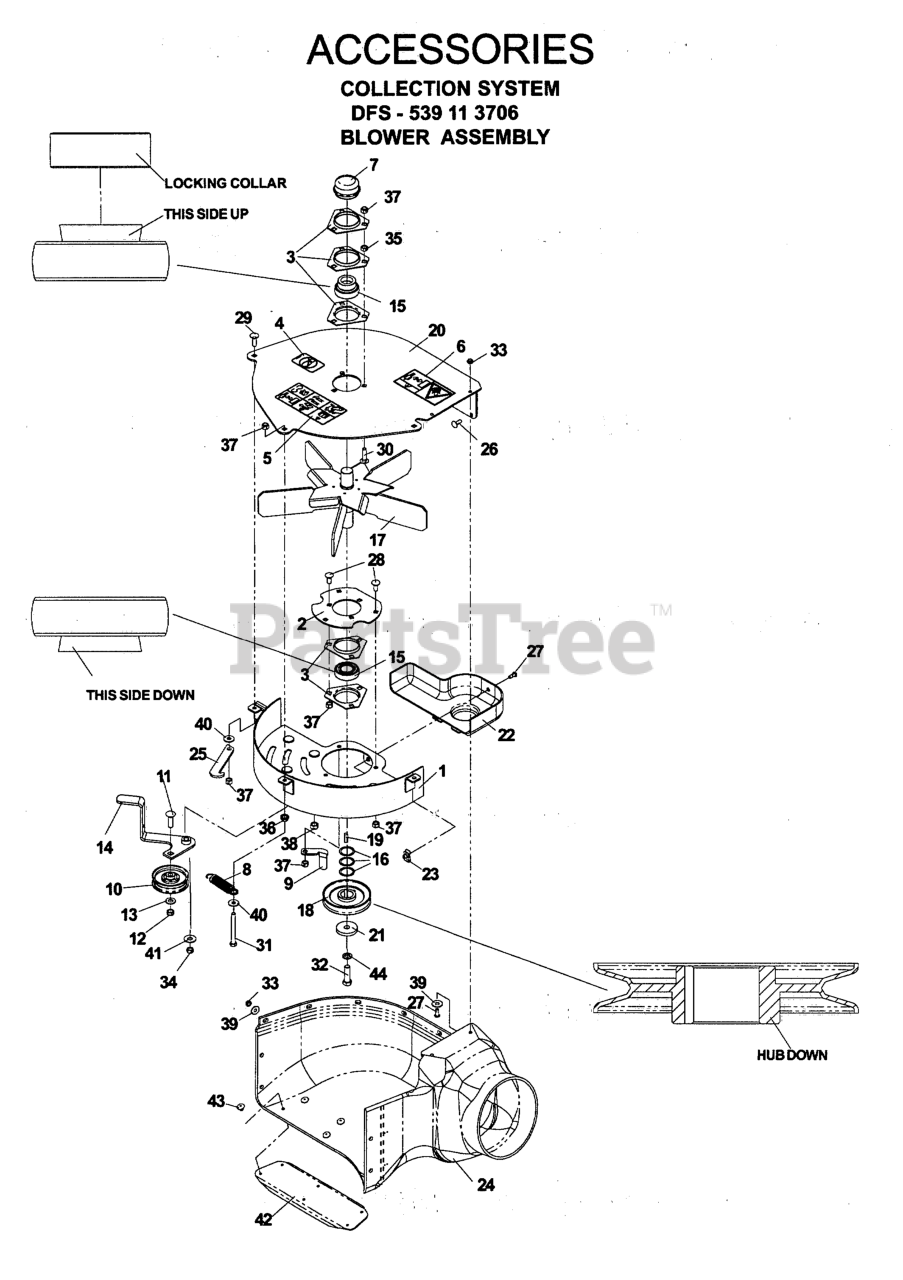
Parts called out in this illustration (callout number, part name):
1	FLOOR WELDMENT
2	BEARING PLATE
3	BRG FLANGE
4	DECAL, NO STEP
5	DECAL, EURO WARNING
6	EURO DECAL, IMPELLER
7	GREASE CAP
8	SPRING-TRANS
9	BELT GUIDE
11	RHSNB 3/8-16 X 1-1/4
12	NUT HEX 3/8-16 NYLON, THIN
13	WASHER 3/8 SAE FLAT
15	BEARING KIT-2 PCS
16	BUSHING.MACHINE.18.GAUGE
17	SPINDLE BLOWER FAN
19	KEY 1/4 SQ X 3/4
20	FAN COVER W/DECALS
21	SPINDLE WASHER
22	PULLEY SHEILD
23	1/4C - U TYPE RETAINER
24	BLOWER HOUSING
25	KEEPER, IDLER
26	RHSNB 1/4C X 3/4
27	SCR 1/4-20 X 5/8 BTN SKT HD ZD
28	RHSNB, 5/16 X 3/4
29	RHSNB 5/16C X 1
30	BOLT, CARRIAGE 5/16X1-1/4
31	HCS 5/16C X 2-3/4
32	HCS 7/16F X 1 1/2
33	JAM NUT 1/4C (2 2 PW01)
34	NUT, 5/16C, CENTERLOCK
35	NUT 5/16C HEX
36	NUT 5/16C WHIZ
37	NUT 5/16 NYLOC
38	NUT 3/8-16 NYLOC
39	WASHER 1/4 FLAT
40	WASHER 5/16 FLAT
41	WASHER 3/8 FLAT
42	BLOWER SUPPORT
43	RIVET E/16 X 1/4 LG FLG
44	WASHER 7/16 LOCK
